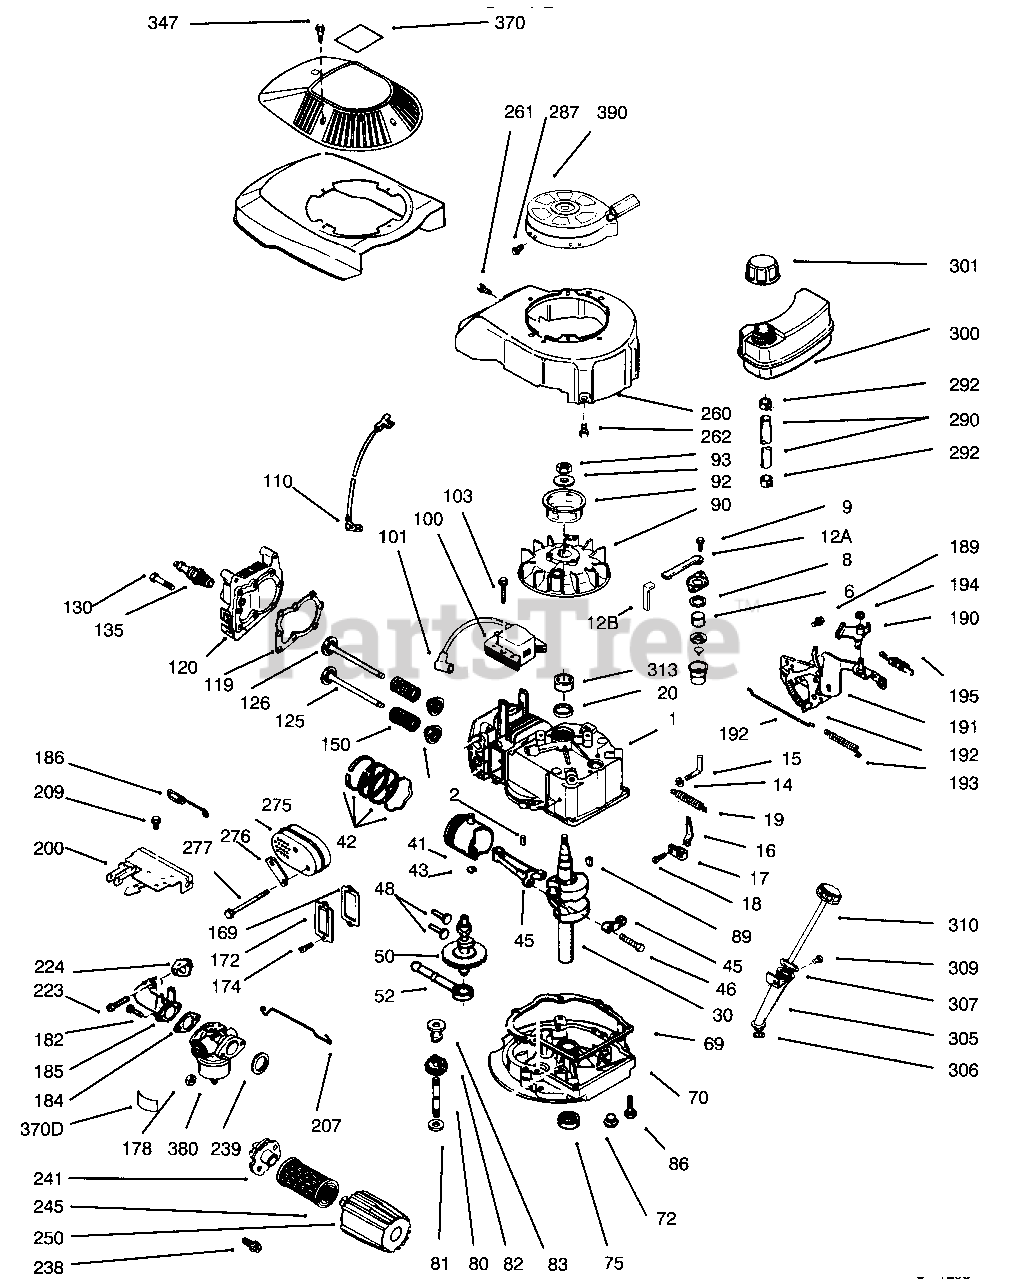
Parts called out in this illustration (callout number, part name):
1	Cylinder (Incl. Ref. #2, 8, 9 & 10)
2	Pin-Dowel
6	Element-Element
8	Gasket-Breather
12A	Tube-Breather
12B	Elbow-Breather Tube
14	Washer-Flat
15	Rod-Governor
16	Lever-Governor
17	Clamp-Governor Lever
19	Spring-Extension
20	Seal-oil
30	Crankshaft
41	Piston & Pin Assembly (.010 O.S. Incl. Ref. #43)
42	Set-Rings (Std)
43	Retainer-Piston Pin
45	Rod-Connecting (Incl. Ref. #46)
46	Bolt-Connecting Rod
48	Lifter-Valve
50	Camshaft
52	Oil Pump Assembly
70	Flange-Mounting (Incl. Ref. #72, 75, 80, 82, 83, 311 & 312)
72	Plug-Oil
75	Seal-Oil
80	Shaft-Governor
81	Washer-Flat
82	Governor Shaft Assembly
83	Spool-Governor
89	Key-Flywheel
90	Flywheel
92	Washer-Belleville
93	Nut-Flywheel
100	Solid State
101	Cover-Spark Plug
110	Wire-Ground
119	Gasket-Cylinder Head
120	Head-Cylinder
125	Valve-Exhaust (1/32 O.S. Incl. Ref. #151)
126	Valve-Intake (1/32 O.S. Incl. Ref. #151)
135	Spark Plug (RJ19LM)
150	Spring-Valve
151	Cap-Valve Spring
169	Gasket-Valve Spring
172	Cover-Valve Spring
178	Nut/Washer
182	Screw
184	Gasket-Carburetor
185	Pipe-Intake (Incl. Ref. #224)
186	Link-Governor Spring
190	Lever-Brake
191	Bracket-Brake
192	Link-Control
193	Spring-Brake
194	ring-Retaining
195	Terminal
200	Control Bracket Assembly
207	Link-Throttle
224	Gasket-Intake Pipe
239	Gasket-Air Cleaner
241	Collar-Air Cleaner
245	Filter-Air Cleaner
250	Cover-Air Cleaner
260	Housing-Blower
275	Muffler (Incl. Ref. #277)
276	Plate-Lock
285	Hub-Starter
290	Line-Fuel
292	Clamp-Fuel Line
300	Tank-Fuel (Incl. Ref. #292 & 301)
301	Cap-Fuel
302	Retainer-Cap
305	Tube Fill
306	"O" Ring
307	"O" Ring
310	Dipstick
313	Spacer-Flywheel
370	Decal-Caution
370D	Decal-Primer
380	Carburetor (Incl. Ref. #184)
390	Starter-Recoil
